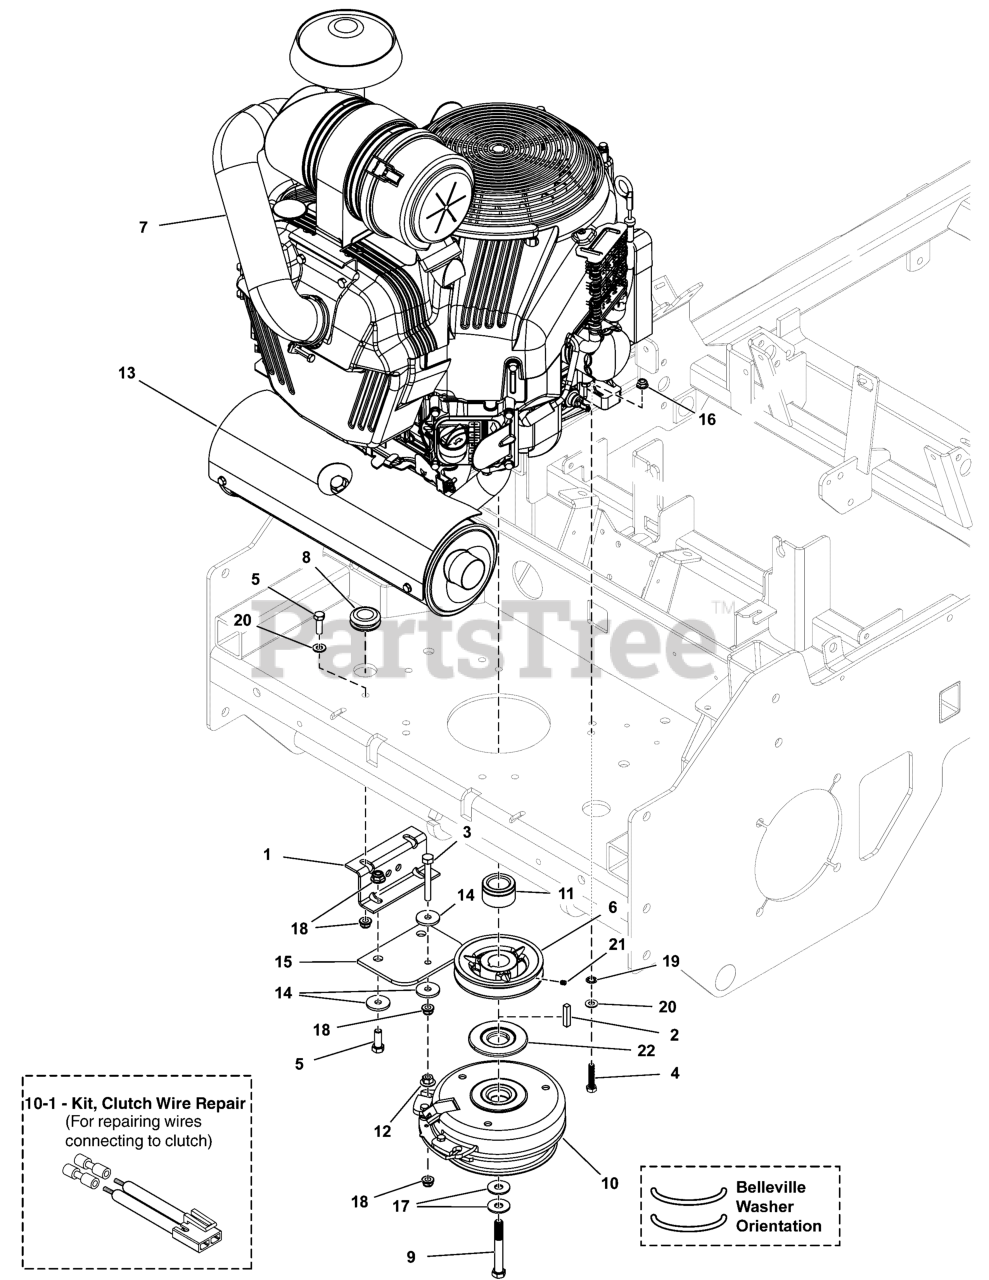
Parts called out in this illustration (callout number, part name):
1	ANCHOR, CLUTCH - BLK
2	KEY, 1/4" SQ. X 1-1/4
3	BOLT, 5/16-18 X 2-1/2 GD5 TFL, CZ
4	BOLT, 5/16-24 X 1-3/4, GD8, PHOS
5	BOLT, 5/16-18 X 1" GRD5 YZ
6	PULLEY, 4.75 OD X 1-1/8 BORE, BC-48
8	GROMMET, 7/8"ID, 1/4" THICK STK
9	BOLT, CRANKSHAFT, 7/16-20 X 3-1/4, GD 8
10	CLUTCH, 250 FT-LBS, WATER GUARD
10-1	KIT, CLUTCH WIRE REPAIR
11	SPACER, 1.13 X 1.75 X 1.35, CZ
12	NUT, 5/16-18 HEX SERRATED FLANGE (LARGE)
13	MUFFLER (Purchase from Engine Manufacturer)
14	WASHER, .34 X 1.25 X 10 GA
15	CLUTCH ANCHOR PAD
16	NUT, 5/16-24, TOP LOCK FLANGE, GD8 PHOS
17	BELLEVILLE WASHER, 1.1875 X .442 X .098
18	NUT, 5/16-18 HEX NYLOCK FLANGE NUT
19	WASHER, 5/16" Internal Tooth Lock
20	WASHER, 5/16" SAE
21	SET SCREW, 5/16-18 X 3/8, KNURL, W/PATCH
22	WATER GUARD, WARNER C 250 FT-LBS CLUTCH
